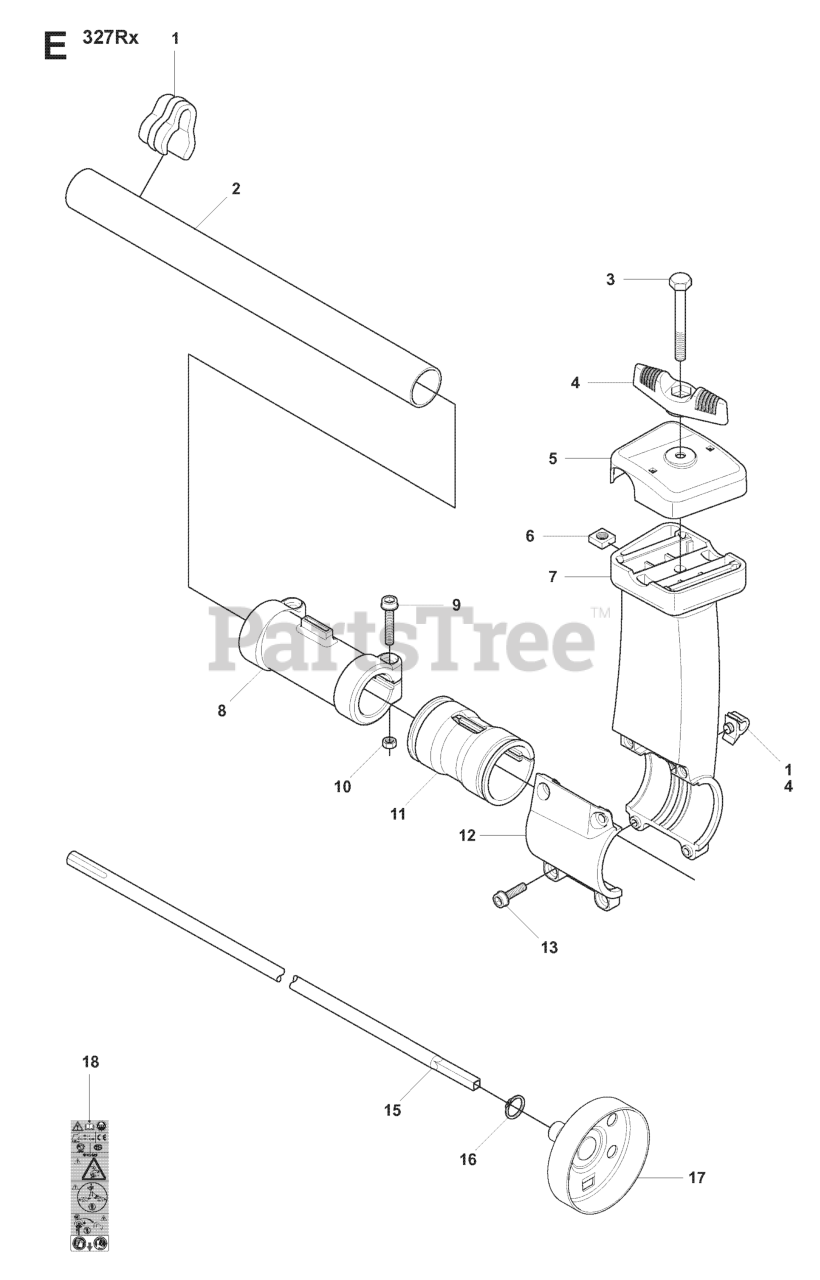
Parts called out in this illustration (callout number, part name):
2	DRIVE TUBE ASSEMBLY
3	%SCREW
5	PROTECTOR CLAMP
7	BRACKET
8	COMPRESSION SLEEVE Ã~24
11	VIBRATIONS ABSORBER
12	COVER, BRACKET
15	DRIVE SHAFT
16	RETAINING RING SGA 10
17	CLUTCH DRUM
18	RP WARNING DECAL
